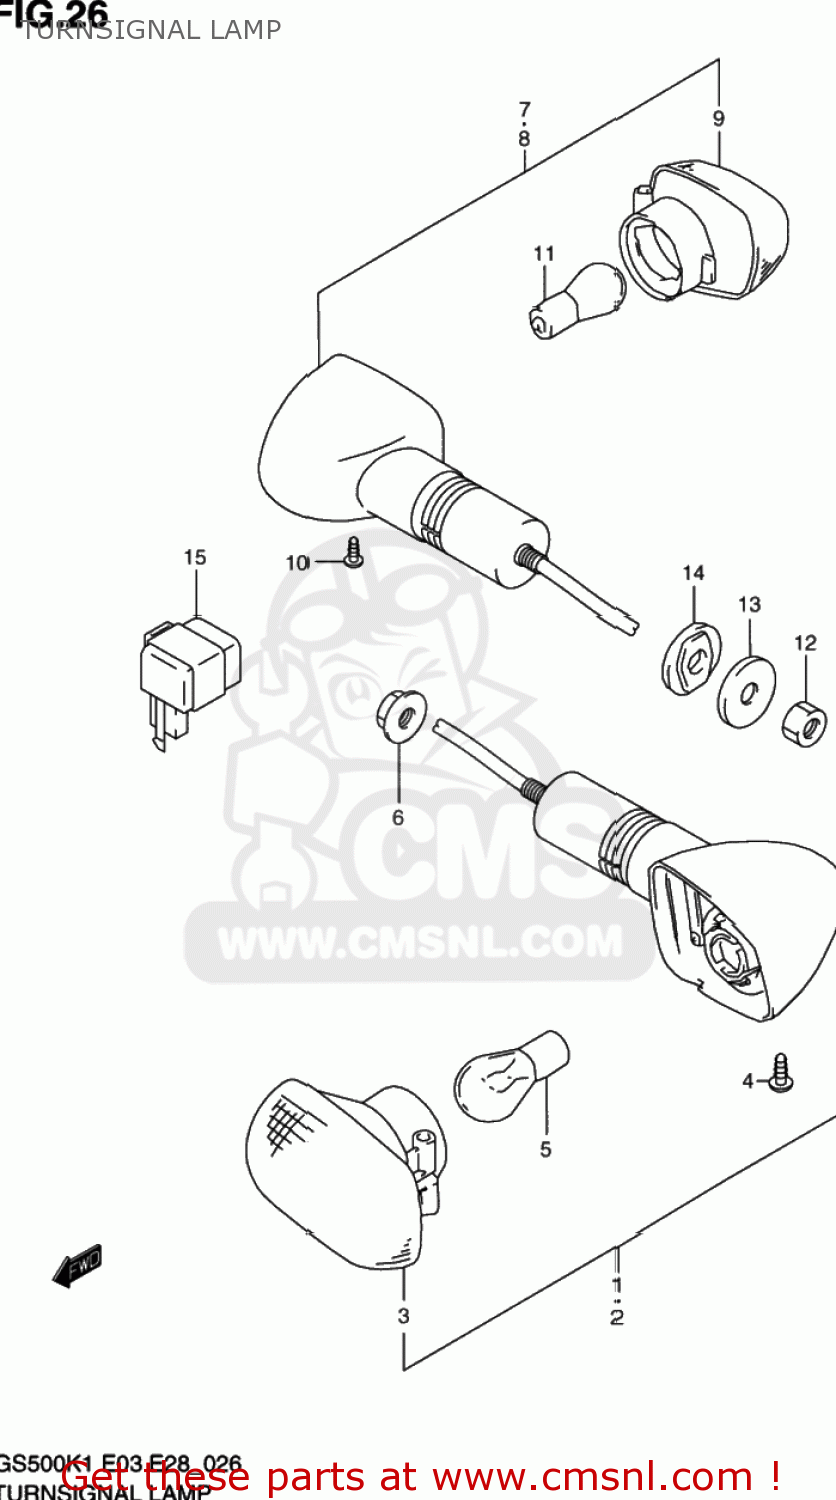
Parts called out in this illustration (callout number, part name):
1	LAMP ASSY,FR TURN SIGNAL,R
2	LAMP ASSY,FR TURN SIGNAL,L
3	LAMP UNIT
4	SCREW
5	BULB(12V21W)
6	NUT
7	LAMP ASSY,RR TURNSIGNAL,R
8	LAMP ASSY,RR TURNSIGNAL,L
9	LAMP UNIT
10	SCREW
11	BULB(12V21W)
12	NUT
13	WASHER(10.5X30X2.3)
14	SPACER,RR TURNSIGNAL
15	RELAY ASSY
